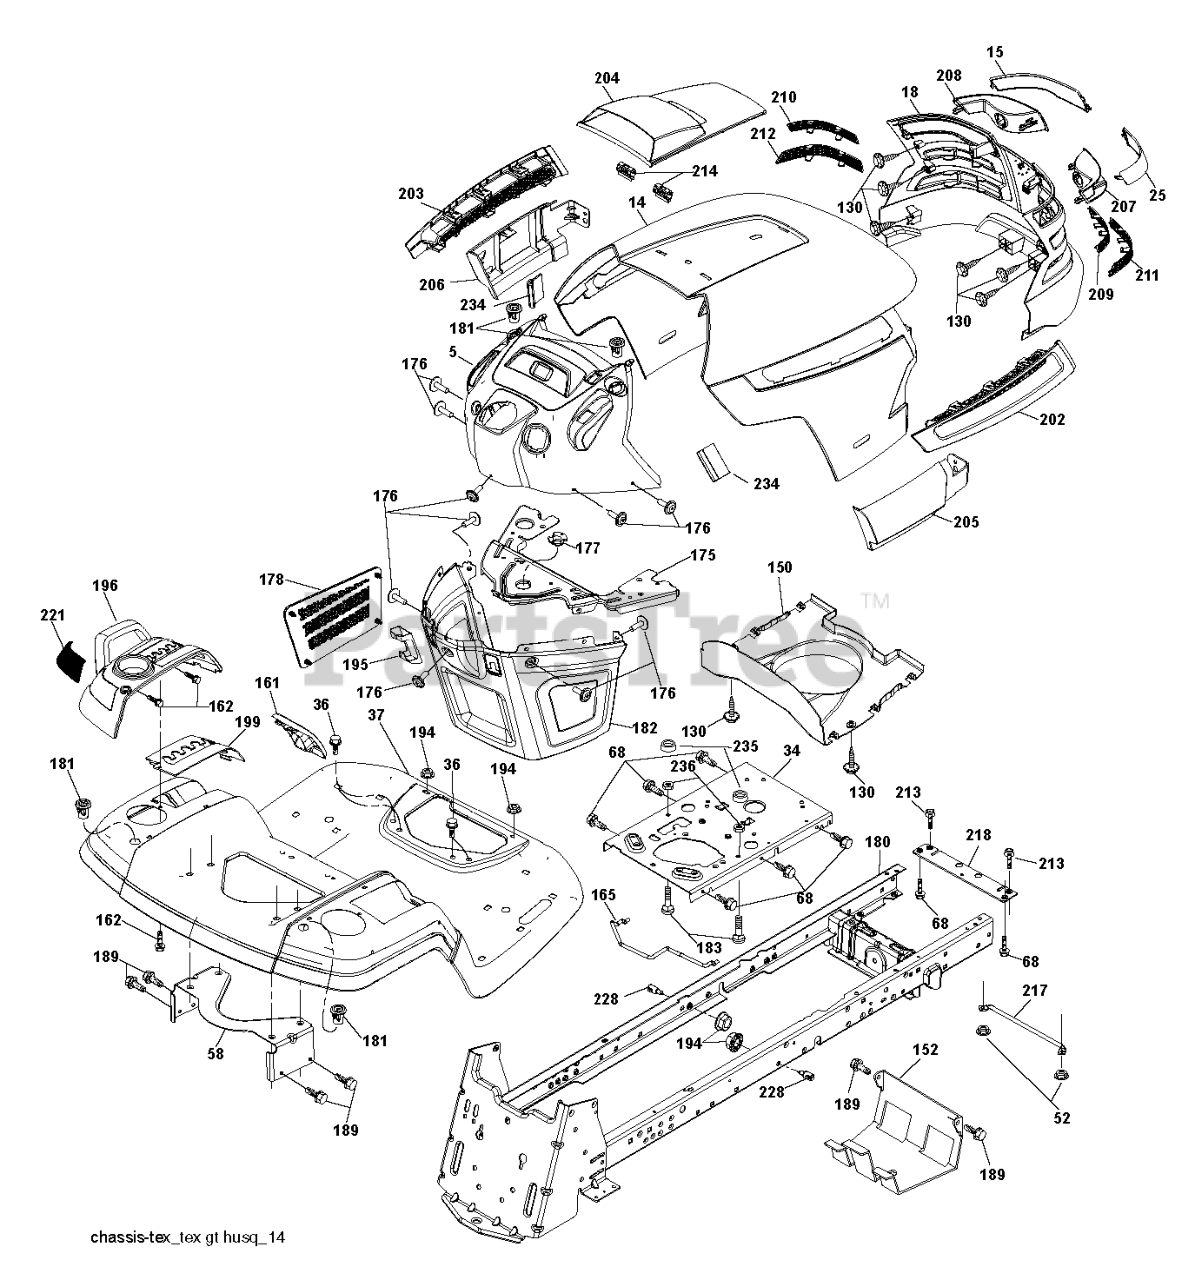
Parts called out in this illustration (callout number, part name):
5	DASH.ASM.HUSQ.GT.E.RECT.W/CK
14	HOOD
15	LENS.LH.TEX.GT.HUSQ.CL
18	GRILL.ASM.HUSQ.TG/CRD.W/TRIM
25	LENS.RH.TEX.GT.HUSQ.CL
34	PLATE.ENGINE.WELDED.CHASSIS
36	SCREW 5/16"
37	FENDER.PNT.TX.GT.CH/FW.ORANGE
52	LOCKNUT
58	BRKT.SUPPORT.FNDR/TANK
68	Screw 5/16-18 x 1/2 Hex, Self Tapping 5/16-18 x 1/2
130	SCREW.#10 X 0.750.BOS
150	AIR.DUCT.HOOD.TEX.GT.HUSQ
152	SHIELD.BROWNING.W/TEX
161	CONSOLE.FUEL.WINDOW.HU
162	SCREW.HI-LO.CONSOLE
165	SUPPORT.TANK.REAR.W/TEX
175	PLATE.CROSSMEMBER.HUSQ
176	SCREW.#10-24X5/8.RN.QU
177	BUSHING, STEERING
178	CARGO.ASM.NET.TXGT.W/C
180	CHASSIS.GT.SLOPED.DRAWBAR.
181	BUSHING.MNT.FEND.CRGO.
182	DASH.LOWER.COMMON.12V.ADAPTOR
183	BOLT.5/16-18X1-1/4 FULL.THREAD
189	SCREW
194	NUT LOCK HEX FLANGE 5/16-18
195	PLUG.N/CRUISE.COMMON.YT/GT.BLK
196	CONSOLE.ASM.DCKLFT.W/RF.HQ.DLR
199	PLATE.DECK.LIFT.HUSQVARNA.GT
202	VENT.SIDE.HOOD.HUSQ.RH.GREY
203	VENT.SIDE.HOOD.HUSQ.LH.GRAY
204	HOOD VENT
205	SKIRT.HOOD.SIDE.HUSQ.RH.GREY
206	SKIRT.HOOD.SIDE.HUSQ.LH.GREY
207	BEZEL.RH.TEX.GT.HUSQ
208	BEZEL.LH.TEX.GT.HUSQ
209	INSERT.HEX.GRILL.HUSQ.GREY
210	INSERT.HEX.GRILL.HUSQ.
211	INSERT.HEX.GRILL.HUSQ.
212	INSERT.HEX.GRILL.HUSQ.
213	BOLT
214	CLIP.RETAINER.TINNER.
217	ROD.PIVOT.HOOD
218	X-PIECE.HOOD.STOP.NON/
221	REFLECTOR.LH.TEX GT HU
228	STUD.FASTNER.W/ANTI-ROTATE
234	BUMPER.HOOD.TEX.HUSQVARNA
235	SPACER FENDER
236	NUT.CENTERLOCK.5/16-
